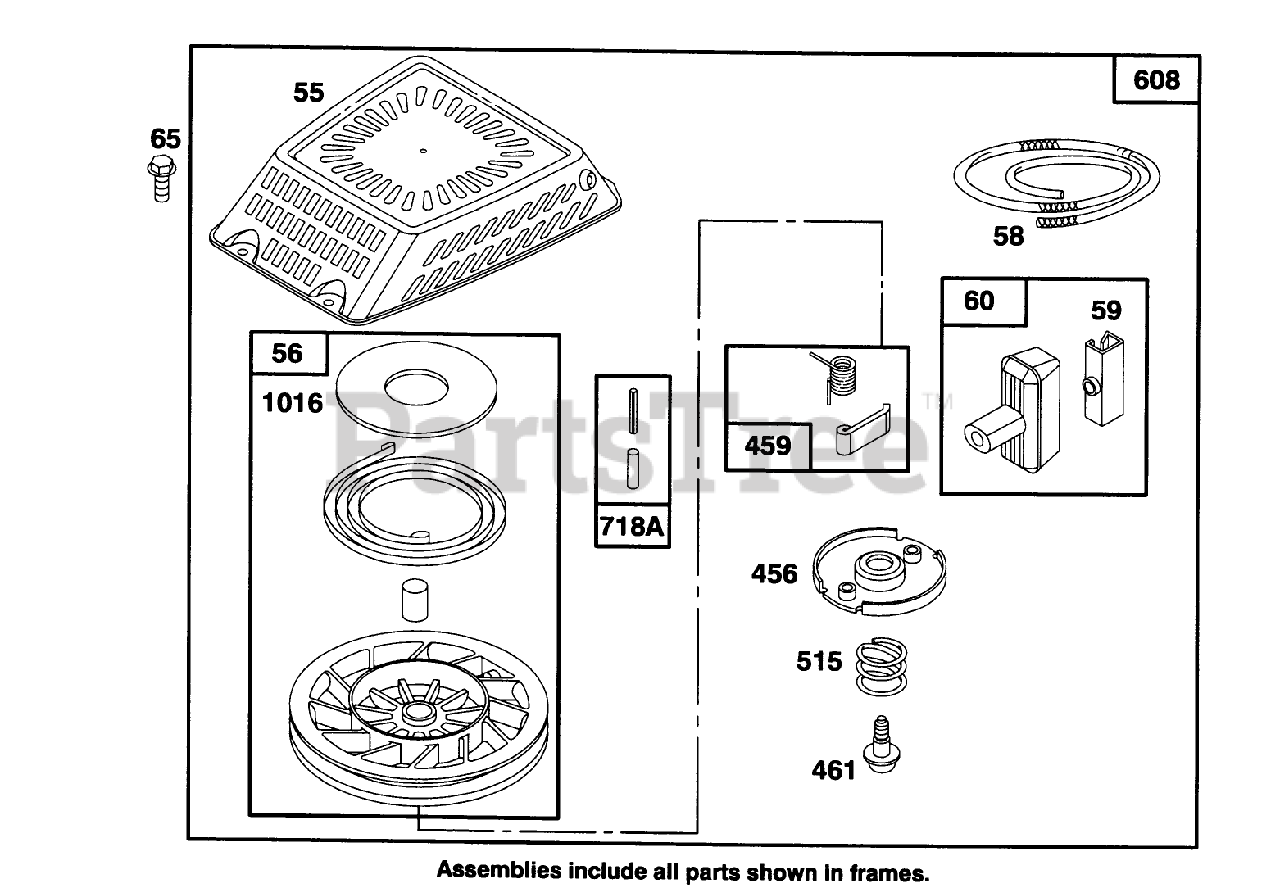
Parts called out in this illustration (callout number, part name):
59	INSERT-HANDLE, REWIND
456	RETAINER - SPRING
515	SPRING - RETAINER
